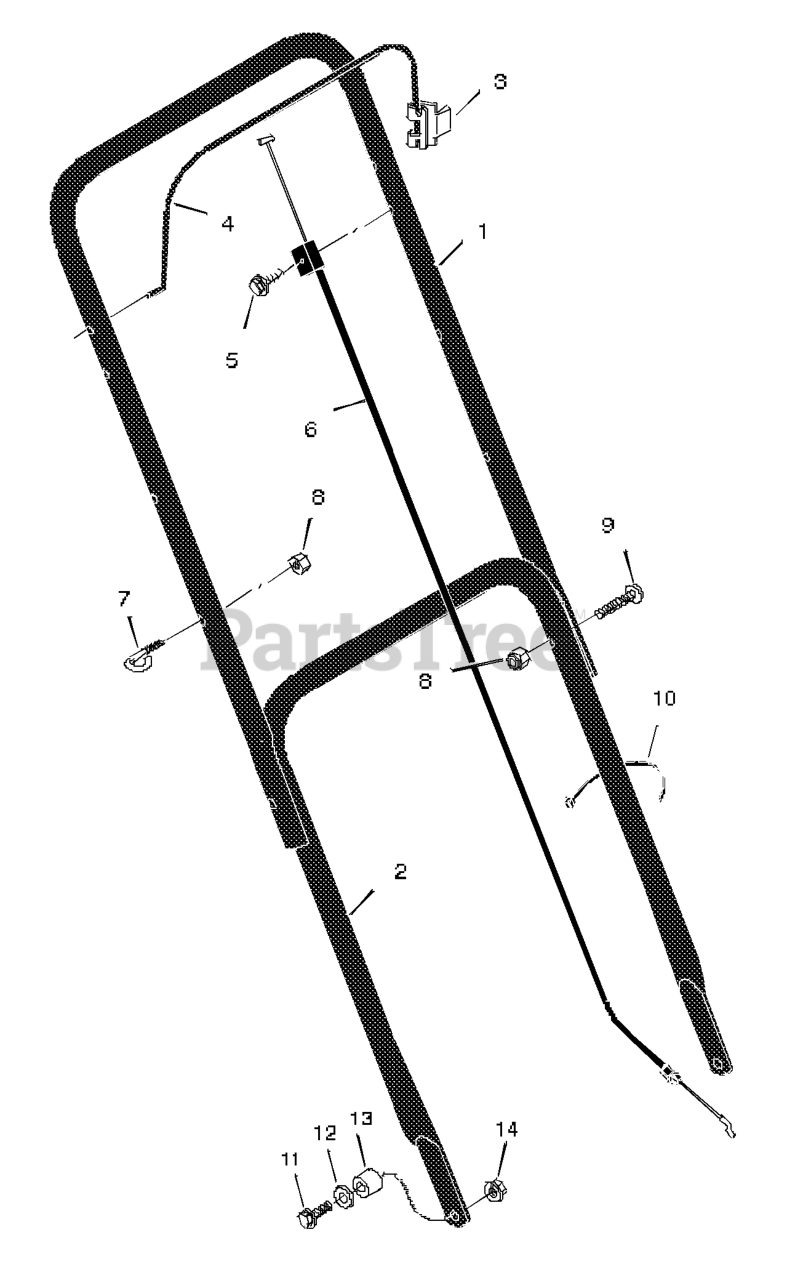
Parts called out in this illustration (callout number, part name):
1	Handle, Upper (Black)
2	Handle, Lower (Black)
3	Bracket, Stop Lever
4	Lever, Stop
6	Engine Stop Cable
7	GUIDE, ROPE
8	Locknut
10	Fastener, Cable
11	Bolt
14	Nut
